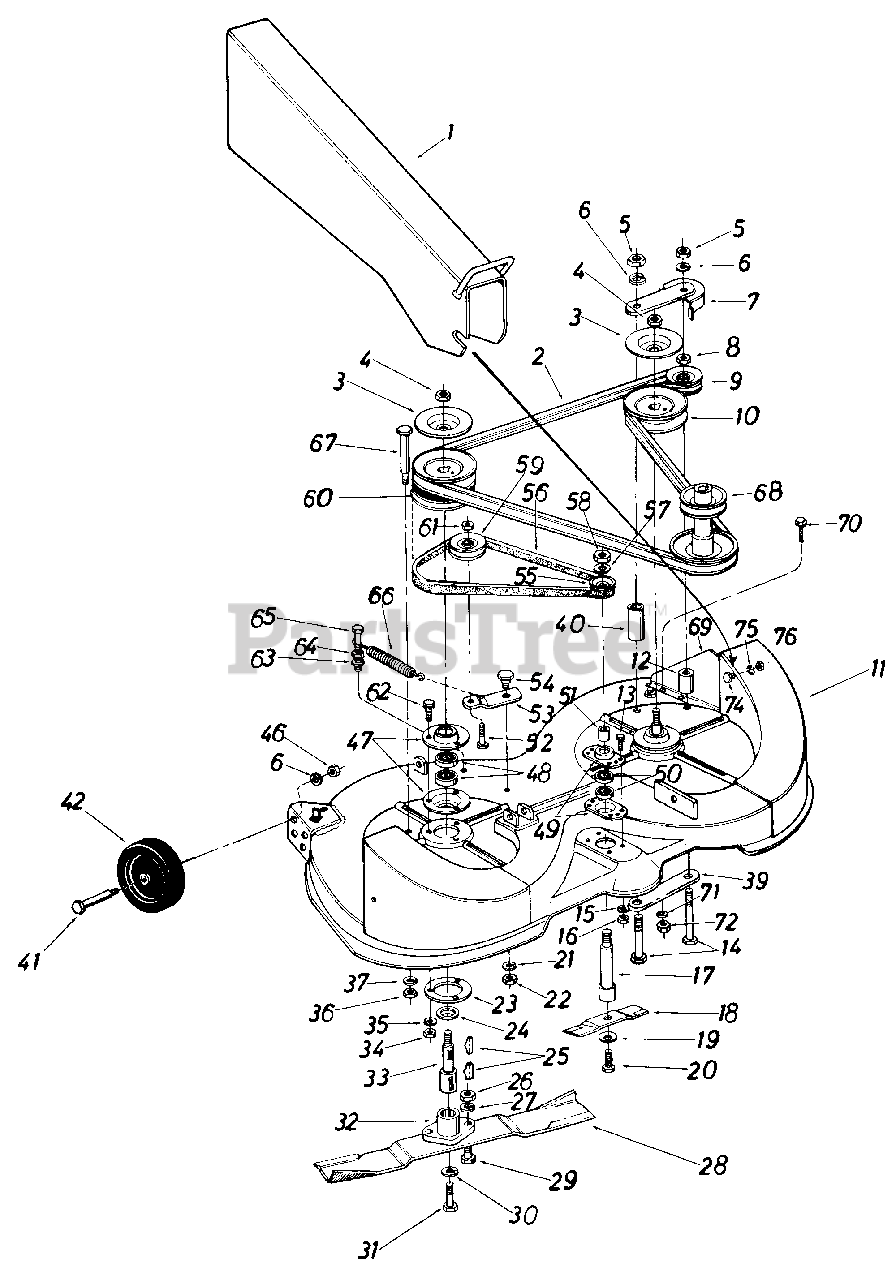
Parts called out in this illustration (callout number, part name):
1	Chute Extension Ass'y. L.H.
2	"V"-Belt 1/2 x 84.0" Lg.
3	Brake Disc
4	Hex Cent. L-Nut 5/8-11 Thd.
5	Hex Jam Nut 3/8-16 Thd.
6	L-Wash. 3/8 I.D.
7	Idler Pulley Belt Guard Ass'y.
8	Hex Jam Nut 3/8-16 Thd.
9	5/8-V Belt Idler 3.50" O.D.
10	5/8-V Pulley .628" I.D. x 5.25 O.D.
11	40" Rear Discharge Deck
12	Spacer.40" I.D. x 1.25" O.D. x 1.59" Lg.
13	Hex Sems Bolt 1/4-28 x .62" Lg.
14	Hex Bolt 3/8-16 x 3.75" Lg.
15	L-Wash. 1/4" I.D.
16	Hex Nut 1/4-28 Thd.
17	Blade Spindle
18	6.50" Blade
19	Bell-Wash. .40" I.D. x .88" O.D.
20	Hex Bolt 3/8-24 x .87" Lg.
21	L-Wash. 3/8 I.D.
22	Hex Nut 3/8-16 Thd.
23	Plate Deck Reinforcement
24	Bearing Shield
25	#6 Hi-Pro Key 5/32 x 5/8" Dia.
26	Hex Nut 5/16-24 Thd.
27	L-Wash. 5/16" I.D.
28	20" High Lift Blade R.H.
29	Hex Bolt 5/16-24 x 1.00" Lg. Grade 5
30	L-Wash. 3/8 I.D. Heavy Duty
31	Hex Bolt 3/8-24 x 1.50" Lg. Grade 5
32	Blade Adapter Kit
33	Blade Spindle
34	Hex Nut 5/16-18 Thd.*
35	L-Wash. 5/16" I.D.
36	Hex Nut 3/8-16 Thd.
37	L-Wash. 3/8 I.D.
39	Reinforcement Plate
40	Spacer 3/8 I.D. x .50" O.D. x 2.72"
41	Shld. Bolt .498" Dia. x 1.53" Lg.
42	Cutting Deck Wheel
46	Hex Jam Nut 3/8-16 Thd.
47	Bearing Housing
48	Ball Bearing .787" I.D. x 1.85" O.D.
49	Bearing Housing
50	Ball Bearing .63" I.D. x 1.38" O.D.
51	Spacer.63" I.D. x .88" O.D. x 1.25" Lg.
52	Hex Bolt 3/8-16 x 1.25" Lg.
53	Idler Bracket
54	Shld. Bolt .625" Dia. x .170" Lg.
55	3/8" V-Pulley .628" I.D. x 2.00" O.D.
56	"V"-Belt 3/8 x 39.0" Lg.
57	Bell-Wash. .63" I.D. x 1.05" O.D.
58	Hex Jam Nut 5/8-11 Thd.
59	1/2" V-Belt Idler 2.625" O.D.
60	Double Pulley
61	Hex Top L-Jam Nut 3/8-16 Thd.
62	Hex Sems Bolt 5/16-18 x 1.00" Lg.
63	L-Wash. 1/4" I.D.
64	Hex Nut 1/4-20 Thd.
65	Hex Bolt 1/4-20 x 1.00" Lg.
66	Ext. Spring .50" O.D. x 3.97" Lg.
67	Shld. Bolt .498" Dia. x 2.63" Lg.
68	Two Step Engine Pulley
69	Inner Chute Extension L.H.
70	Hex Sems Scr. 1/4-28 x .62" Lg.
71	L-Wash. 1/4" I.D.
72	Hex Nut 1/4-28 Thd.
74	Shld. Scr. .500" Dia. x .218
75	L-Wash. 3/8" I.D.
76	Hex Jam Nut 3/8-16 Thd.
